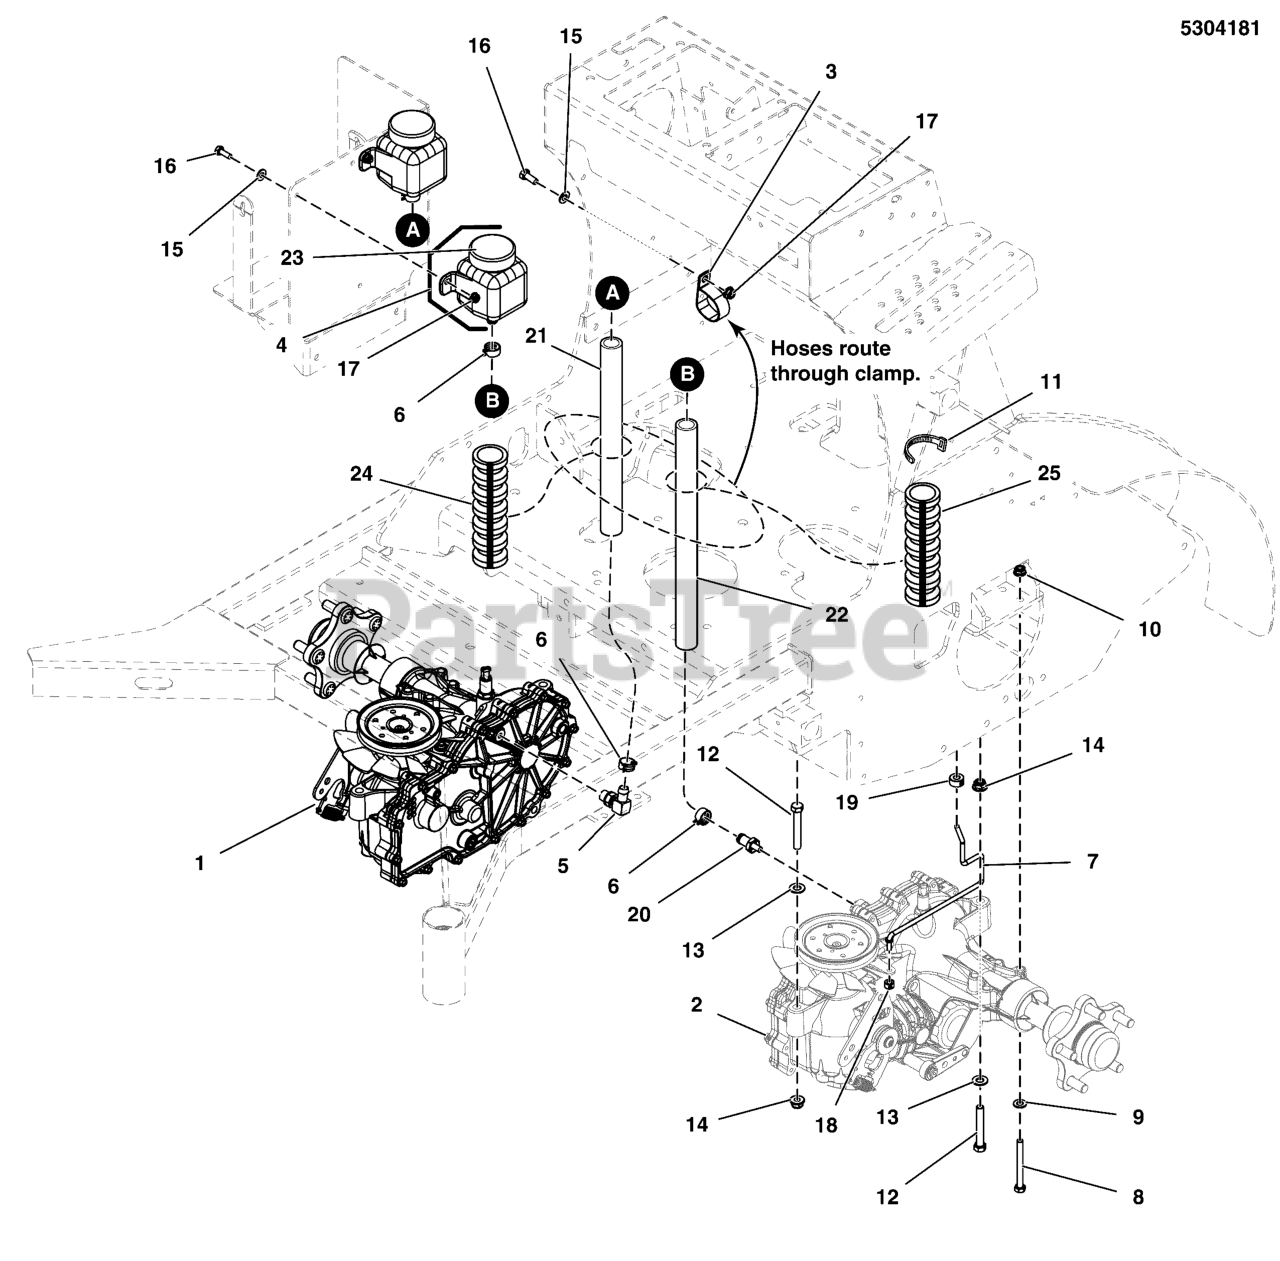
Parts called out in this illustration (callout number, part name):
1	TRANSAXLE, ZT3400, RH, ZU-GKEF-3L7B-1UXE
2	TRANSAXLE, ZT3400, LH ZU-KKEF-3L7C-1UXE
3	CLAMP, VINYL INSULATED, 1.00
4	HYDRO RES. #71328, 350 ml
5	FITTING, 9/16 O-RING-1/2" HOSE, 90 DEG
6	CLAMP, #6 HOSE, STAINLESS
7	ROD, HYDRO RELEASE, STAND ON
8	BOLT, 5/16-18 X 3 GD5 CZ
9	WASHER, 5/16" SAE
10	NUT, 5/16-18 HEX NYLOCK FLANGE
11	TIE, SELF-LOCKING, 6"
12	BOLT, 3/8-16 X 2-1/2" GD5 CZ
13	WASHER, 3/8 SAE
14	NUT, 3/8-16 HEX NYLOCK FLANGE
15	WASHER, 1/4 SAE
16	BOLT, 1/4-20 X 3/4 GD5 CZ
17	NUT, 1/4-20 HEX NYLOCK FLANGE
18	COLLAR, 1/4 SET
19	COLLAR, 5/16 SET
20	FITTING,#6 O-RING-1/2 HOSE BARB,STRAIGHT
21	HOSE, 1/2" PUSH-ON, 30.00"
22	HOSE, 1/2" PUSH-ON, 39.00"
23	RESERVIOR CAP
24	LOOM, CONVOLUTED SPLIT, 1" ID - 8" LONG
25	LOOM, CONVOLUTED SPLIT, 1" ID - 16" LONG
